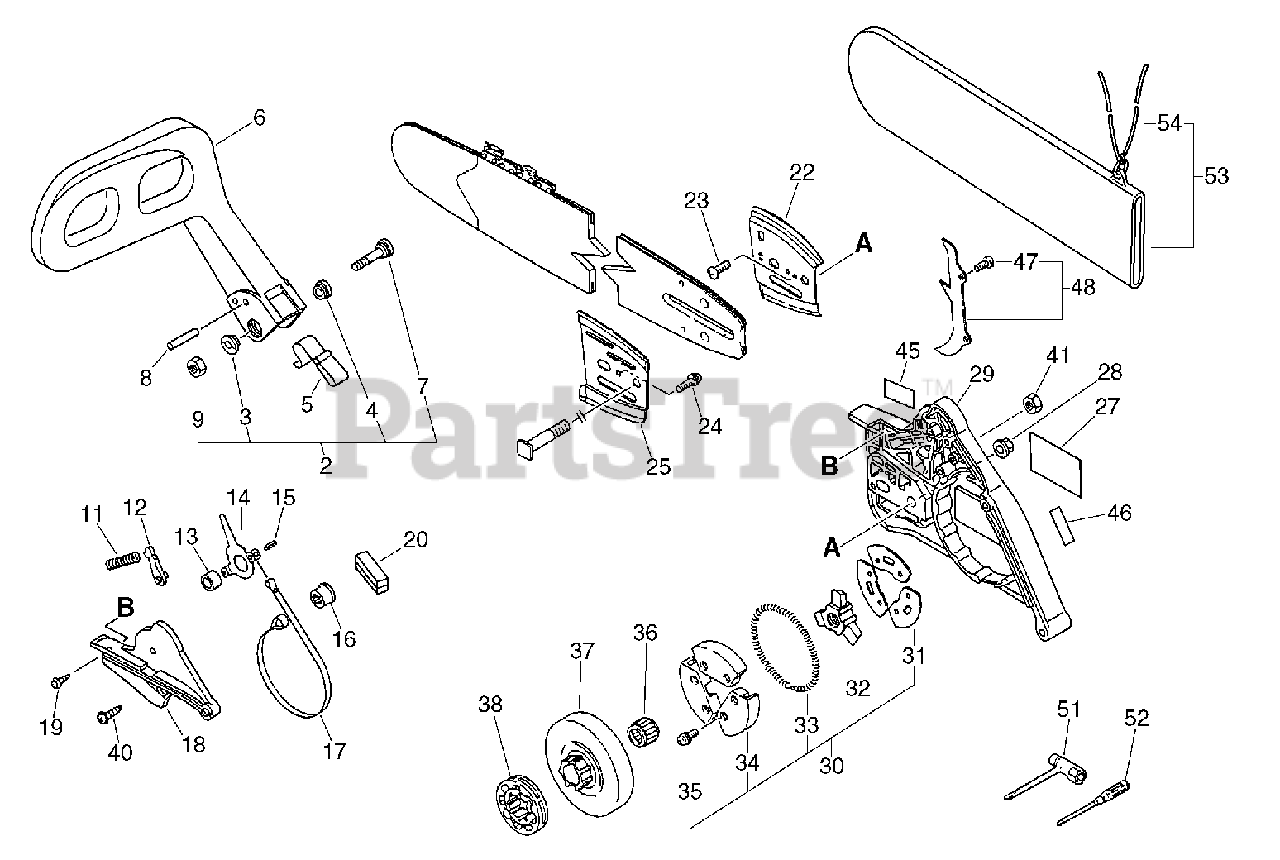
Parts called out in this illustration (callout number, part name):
2	MOUNTING KIT
3	COLLAR 5.3×10×13×L5
4	COLLAR 5
5	SPRING, FLAT
6	LEVER, BRAKE
7	SCREW 5×35
8	PIN 3.5×26
9	NUT, LOCK M5
11	SPRING, BRAKE
12	STOPPER, BRAKE
13	SPACER 8×12×9
14	LEVER, BRAKE
15	PIN, SPRING 4×8.8
16	ADJUSTER, BRAKE
17	BAND, BRAKE
18	COVER, BRAKE
19	SCREW 4×12
20	SEAL, BRAKE
22	PLATE, GUIDE - OUTER
23	SCREW 3×6
24	SCREW 4×8
25	PLATE, GUIDE - INNER
27	LABEL, ECHO
28	NUT, FLANGE M8×1.25
29	GUARD, SPROCKET
30	CLUTCH ASSY
31	PLATE, CLUTCH
32	HUB, CLUTCH
33	SPRING, CLUTCH
34	CLUTCH SHOE SET
35	BOLT 4×6
36	BEARING, NEEDLE
37	DRUM, CLUTCH
38	SPROCKET, RIM 3/8"×7T
40	SCREW 3×18
41	NUT 3 MM
45	LABEL, CHAIN BRAKE
46	LABEL, CAUTION
48	SPIKED BUMPER KIT
51	T-WRENCH 13×19×180
52	SCREWDRIVER, PHILLIPS
53	SCABBARD
54	ROPE 5×900
